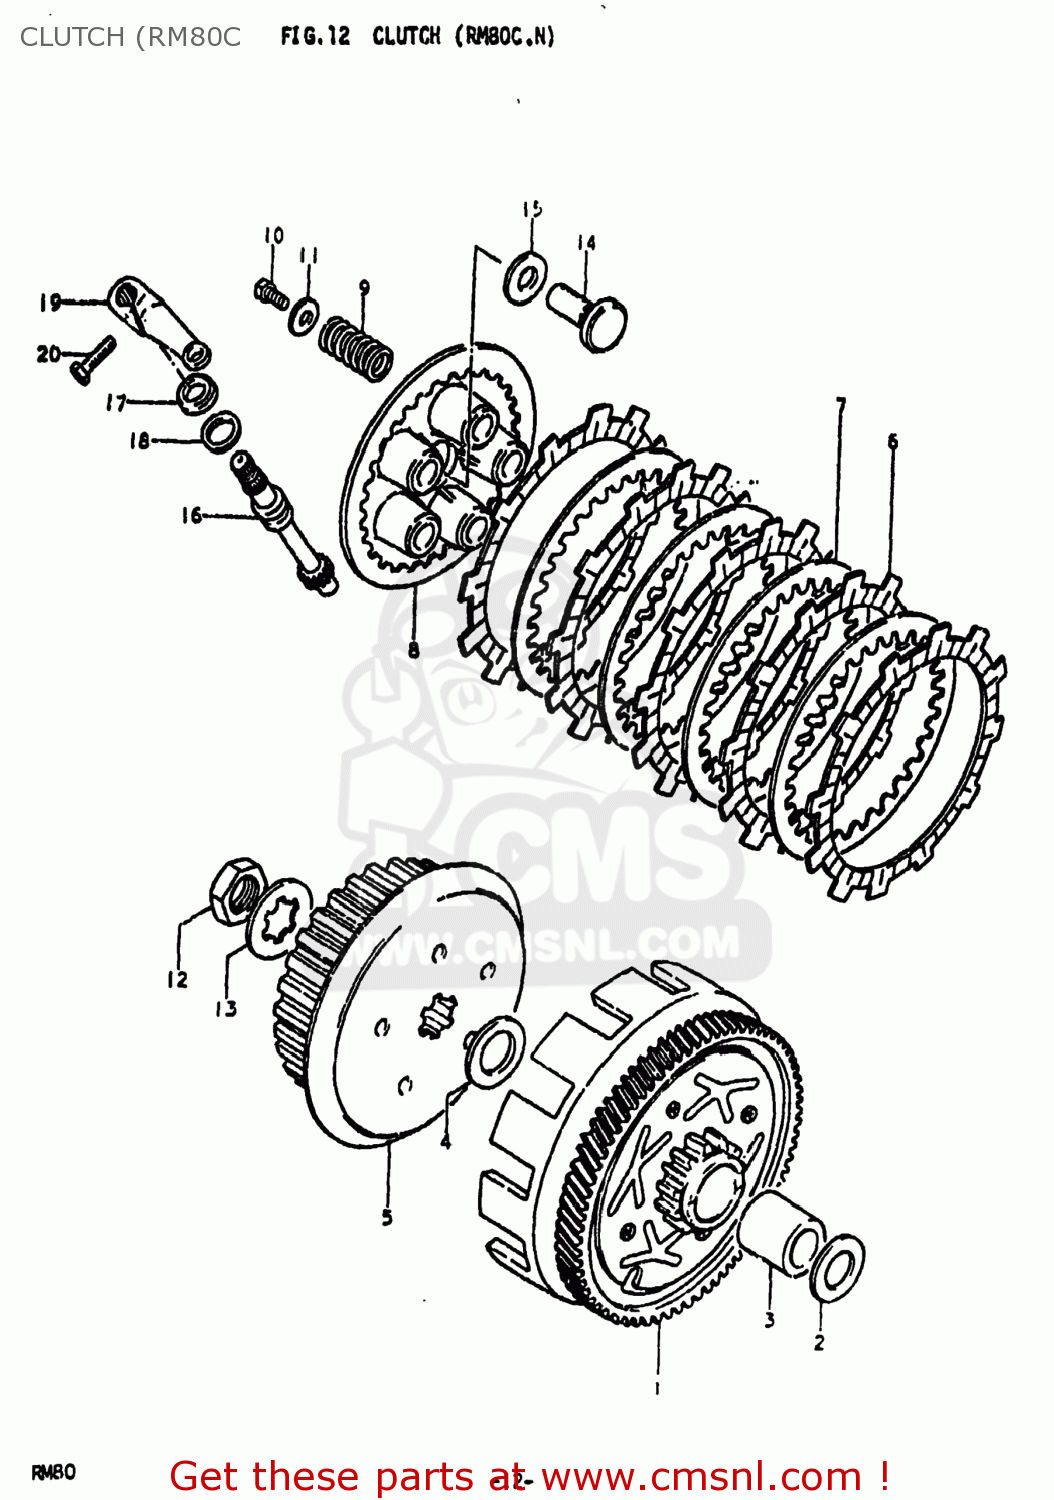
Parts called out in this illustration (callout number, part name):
1	GEAR ASSEMBLY,PRIMARY DRIVE
2	WASHER,THRUST
3	SPACER(17X22X28.5)
4	WASHER
5	HUB,CLUTCH SLEEVE
6	PLATE,CLUTCH DRIVE
7	PLATE,CLUTCH DRIVEN (NAS)
8	DISC,CLUTCH PRESSURE
9	SPRING
10	BOLT(5X16)
11	WASHER (5.5X16X1.2)
12	NUT
13	WASHER,LOCK
14	RACK,CLUTCH RELEASE
15	BEARING(10X22X2.8)
16	PINION,CLUTCH RELEASE
17	OIL SEAL
18	WASHER (12X17X1)
19	ARM,CLUTCH RELEASE
20	BOLT, UPPER
